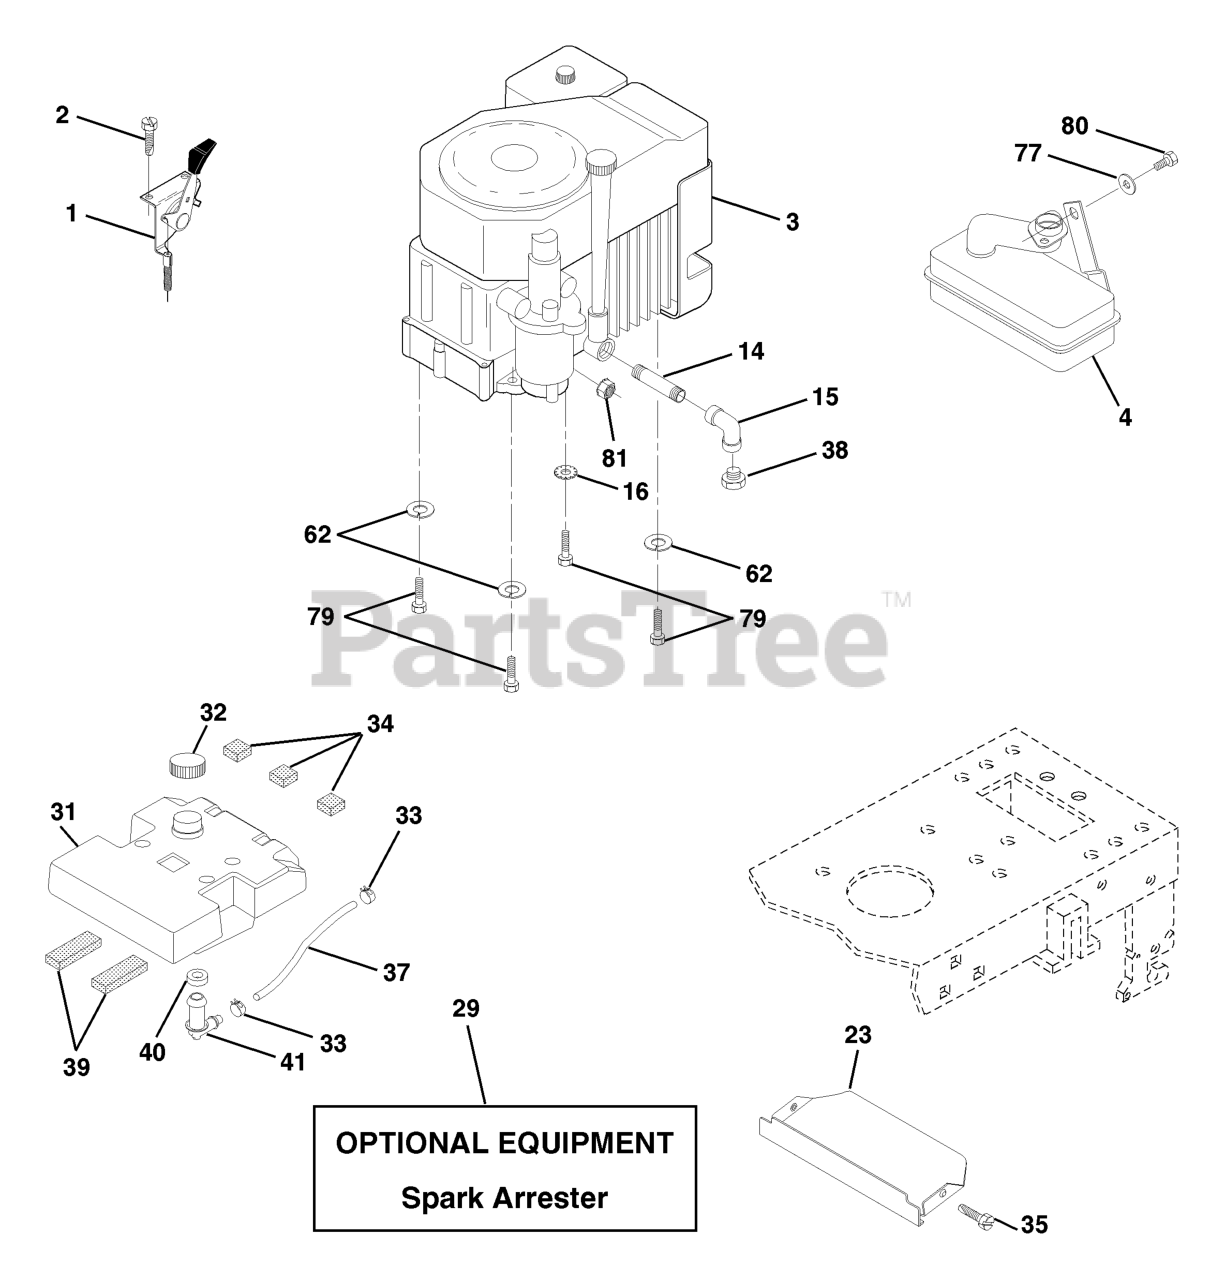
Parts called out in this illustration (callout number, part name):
1	CONTROL SWITCH 27 LH
2	SCREW LT
4	MUFFLER LT 12.5
14	Nipple Pipe 3/8 Npt X 3-1/2
15	ELBOW
16	WASHER EXT TOOTH LOCK 5/16
29	KIT.SPARK ARRESTOR 794945 B&S
31	TANK.FUEL(3.5.GAL)
32	FUEL CAP
33	HOSE CLAMP
34	PAD-SPACER LT
35	SCREW.THDROL.5/16-18X3/4.TTY
37	HOSE T
38	Plug Oil Drain
39	PAD IDLER TI
40	BUSHING OUTLET T
41	STEM FUEL TANK
62	WASHER.LOCK.HVY.HLCL.SPR.5/16
77	WASHER
79	BOLT, HEX
80	Bolt Hex Hd. 5/16-18 unc x 1/2
81	NUT FLANGE 1/4-20 STARTER NUT
